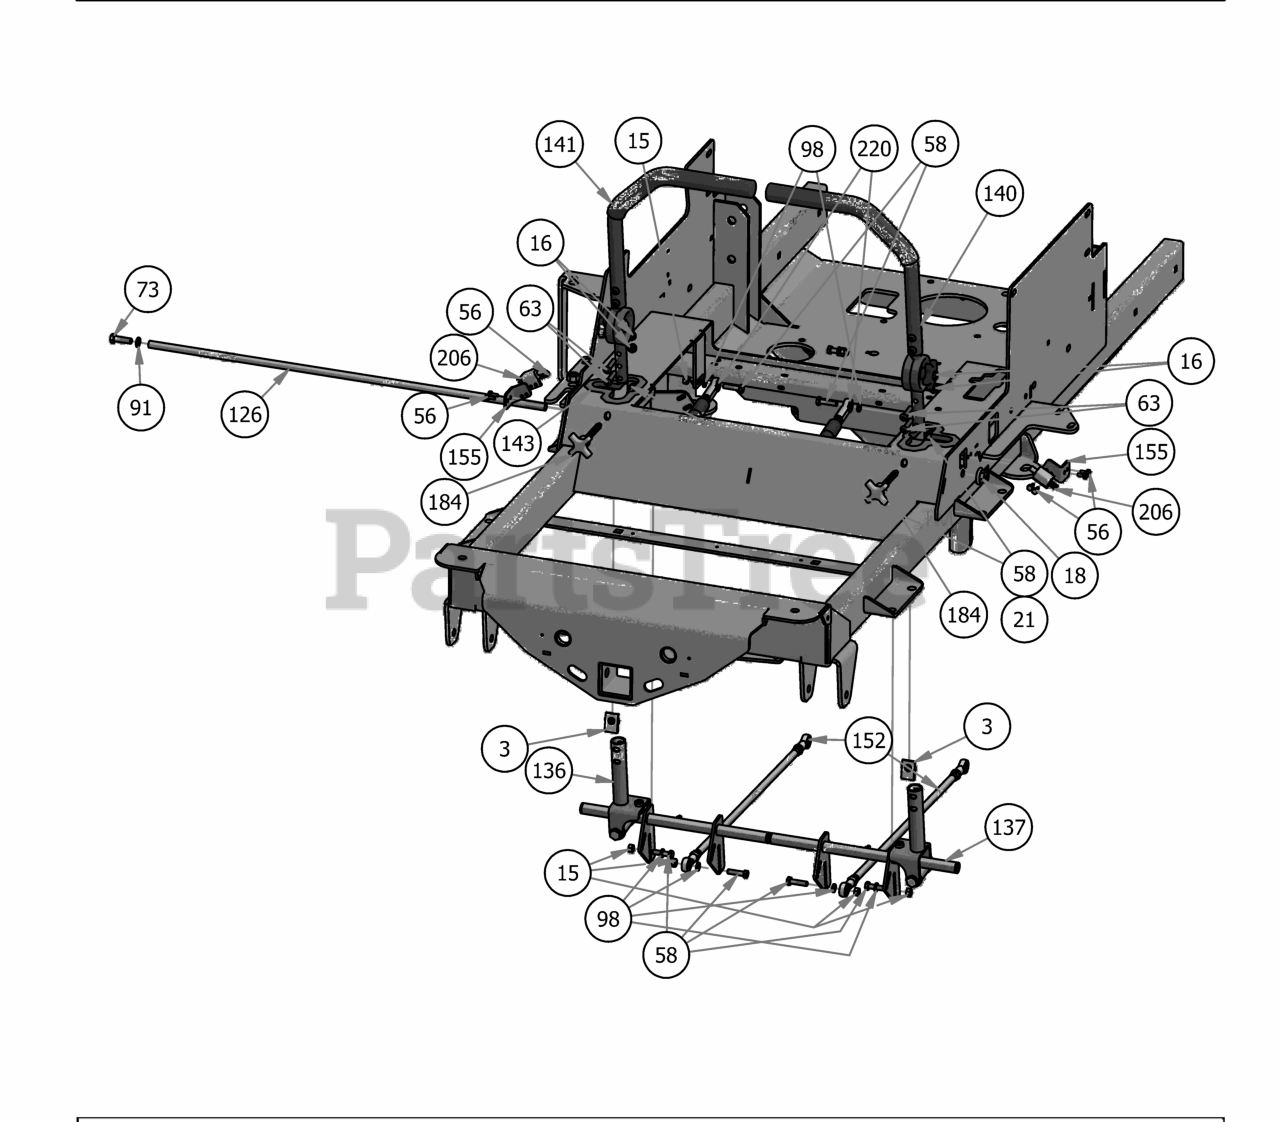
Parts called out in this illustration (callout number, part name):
3	Extruded Nut 3/8"-16 3/4" Hole Center With Patch
15	5/16" Nut
16	5/16-18 Nylock Insert Locknut
18	1/2-13 Nylon Flange Nut
21	5/16" Flange Nut
56	12-24x 1/2 HWH Bolt
58	5/16 x 1 1/4 Hex Bolt
63	5/16-18 BHCS, TORX DRIVE
73	3/8" x 1 1/4" Hex Bolt
91	3/8" Lock Washer
98	5/16" Lock Washer
126	2019 Steering Actuator Rod
136	2019 R Series RH Arm Rod Assembly
137	2019 R Series LH Arm Rod Assembly
140	2019 Left Hand ADJ. Steering Arm Kit
141	2019 Right Hand ADJ. Steering Arm Kit
143	Snap-In Bushing-2019
152	2019 Outlaw Gen2 XP Push Rod Assembly
155	2019 Arm Switch Bracket
184	Speed Limiting Knob 3/8-16X 3"
204	2019 Veritical Suspension Frame
206	Safety Switch
220	2019 SROID Damper With Spherical Rod Ends
